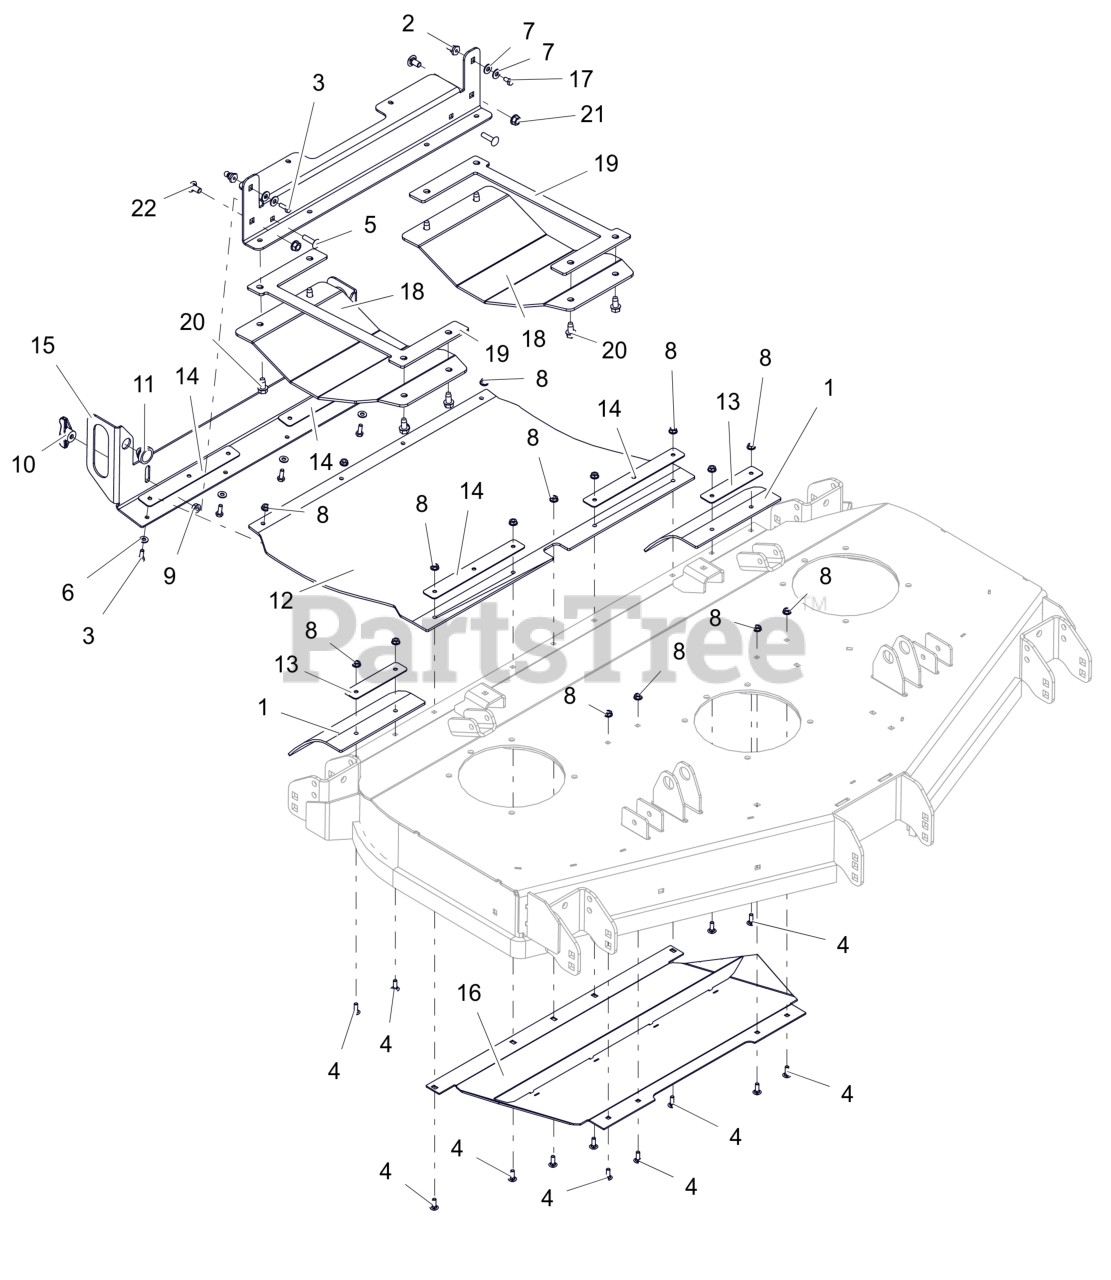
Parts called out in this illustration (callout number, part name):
1	CHUTE- 52" REAR DISCHARGE TIRE
2	STUD, BALL FEMALE .250-20 THREAD
3	BLT, HEX .25-20X.75 G5 ZCC
4	BLT, RHSN .25-20X.750 G5 ZCC
5	BTL,RHSSN .313-18 X 1.25 G5 ZCC
6	WSHR,FLT .281X.625X.065 ZCC
7	WSHR, FLT .312X.734X.065 ZCC
8	NUT-LK-CTR-FLG .25-20 ZC120
9	NUT,LK-CTR-FLG .31-18 GF ZCC
10	KNOB,WING .31-18 UNC NYL/TALC
11	COUPLING, RUBBER PUSH-IN
12	CHUTE- 52" REAER DISCHARGE
13	PLATE- 52" TIRE CHUTE MTG
14	PLATE, CHUTE MTG (BLACK)
15	HANDLE, CHUTE MOUNTING (RED)
16	WLDMT- 52" DEFLECTOR BAFFLE
17	BLT,HEX .25-20X.50 G5 ZCC
18	PLATE, SKID (BLACK)
19	PLATE, SKID TENSION (BLACK)
20	SCR,TAP .375-16X.75 HWH TR ZCC
21	NUT-LK-CTR-FLG .375-16 GF ZCC
22	BLT, RHSSN .38-16X.75 G5 ZCC
